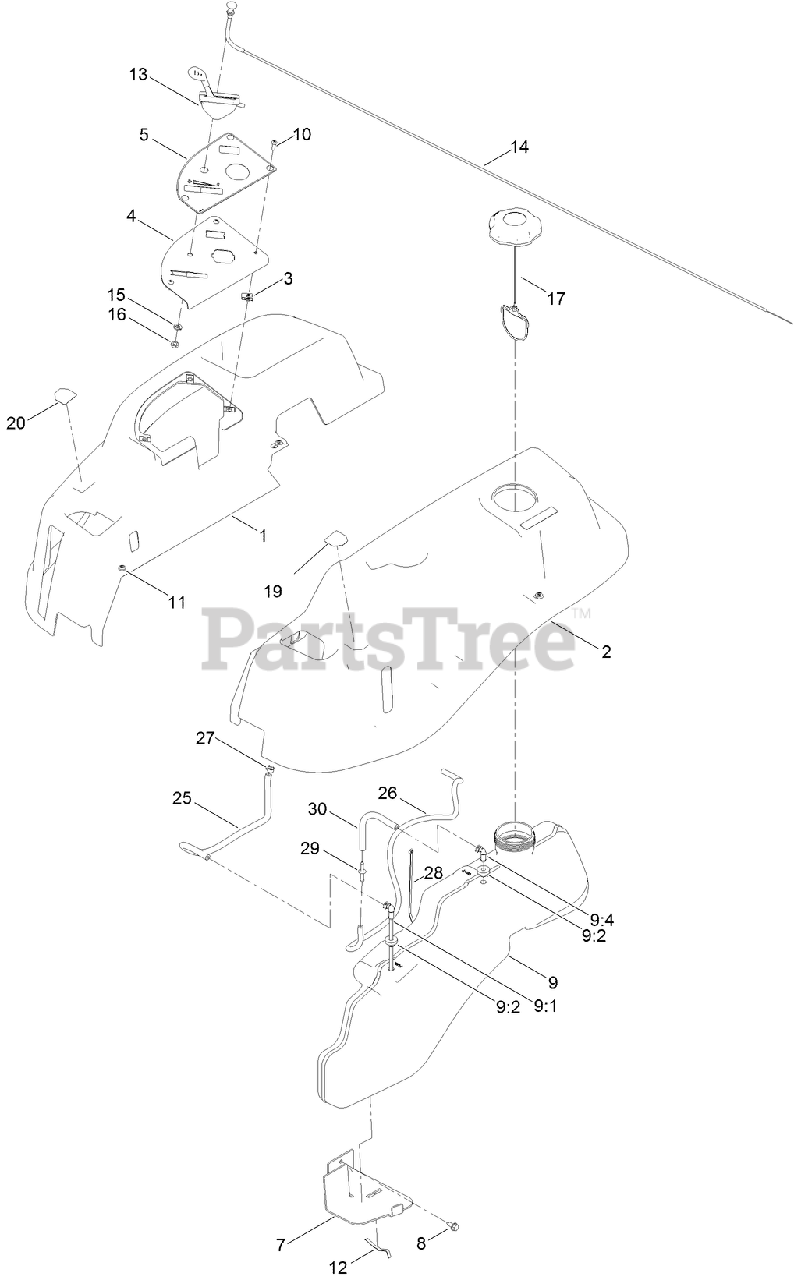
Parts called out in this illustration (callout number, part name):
1	POD-RH
2	POD-LH
4	PLATE-CONTROL
5	DECAL-PANEL, CONTROL
7	SUPPORT-TANK, FRONT
8	SCREW-HWHTF
9	FUEL TANK ASM
9:1	CONNECTOR-ELBOW, 90 DEG
9:2	BUSHING
9:4	FITTING-PLASTIC
10	SCREW-PRH
11	SCREW-SHOULDER
12	SPRING
13	CABLE-THROTTLE
14	CABLE-CHOKE
15	WASHER-LOCK
16	NUT-HJ
19	DECAL-LEVER, CONTROL (LH)
20	DECAL-LEVER, CONTROL (RH)
25	HOSE-FUEL
26	HOSE-FUEL
27	CLAMP-HOSE
28	TIE-CABLE
29	ADAPTOR-ORIFICE
30	HOSE-FUEL
